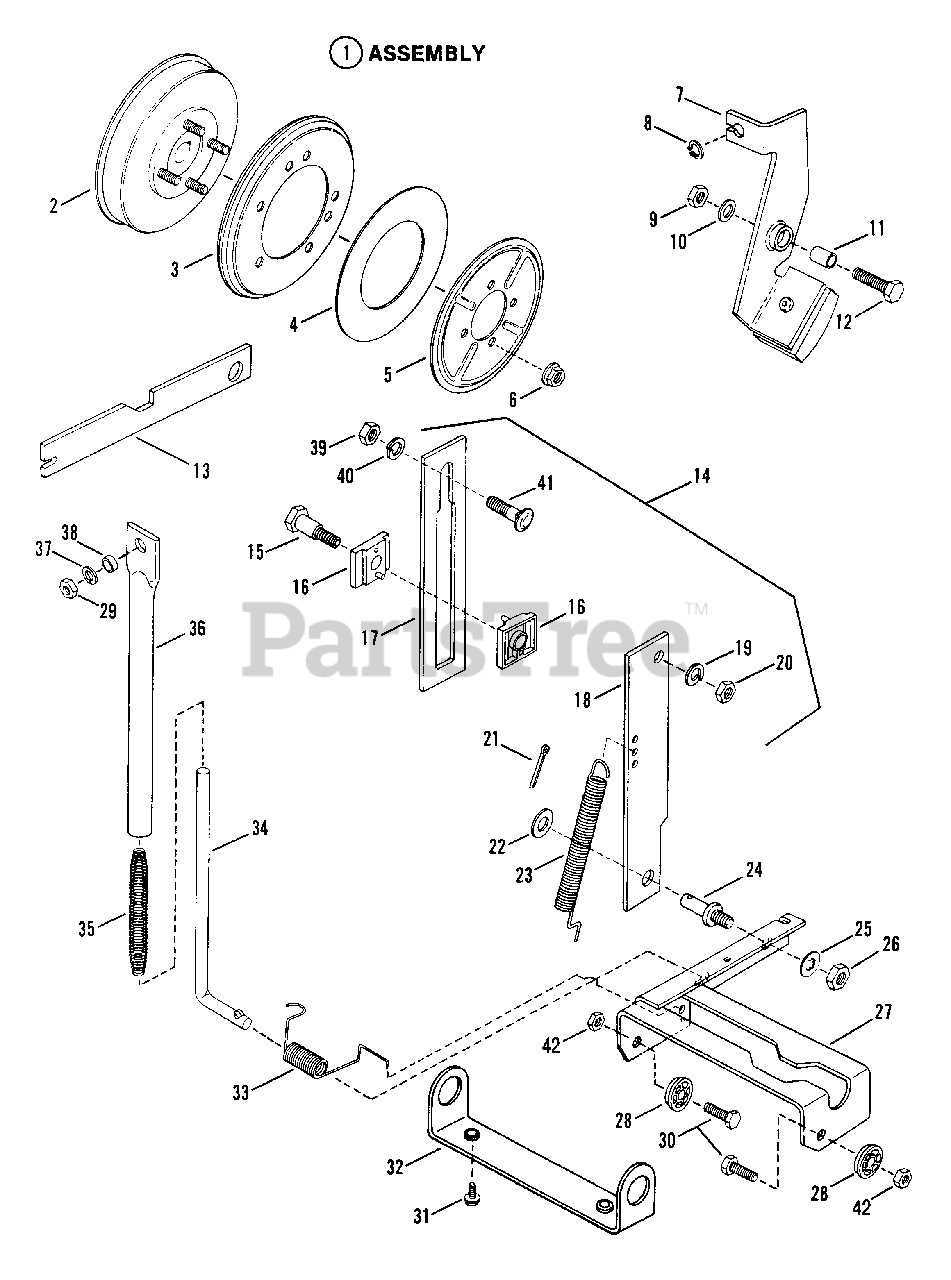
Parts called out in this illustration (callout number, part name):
1	ASSEMBLY, Smooth Clutch
2	HUB, Driven Disc
3	DISC, Driven
4	WASHER, Thrust
5	PLATE
6	NUT, 5/16 - 18 Hex Flange Lock
7	ASSEMBLY, Brake Lever
8	RING, Retaining
9	NUT, 1/4-28 Hex Lock
10	WASHER, 1/4 Flat
11	SPACER
12	SCREW, 1/4-28 x 1" Hex Head Cap
13	TOOL, Smooth Clutch
14	ASSEMBLY, Guide & Link
15	BOLT, 5/16-18 Shoulder
16	SLIDE-HALF
17	GUIDE, Clutch Link
18	LINK, Clutch
19	WASHER, 5/16 Split Lock
20	NUT, 5/16-18 Hex
21	COTTER-PIN, 3/32 x 1"
22	WASHER, 3/8" Flat
23	SPRING, Clutch Brake
24	STUD, Clutch Link
25	WASHER, 3/8 Internal Tooth Lock
26	NUT, 3/8 Hex
27	LIFT, Yoke
28	BEARING, Yoke
29	NUT, 5/16-24 Hex Center Lock
30	SCREW, 5/16-24 x 3/4" Hex Head Cap
31	SCREW, 3/8-16 x 1/2" Self-Tapping
32	COLLAR, Yoke
33	SPRING
35	SPRING
37	WASHER, 5/16 Flat
38	ROLLER
39	NUT, 3/8-16 Hex
40	WASHER, 3/8 Split Lock
41	BOLT, 3/8-16 x 3/4" Short Neck Carriage
42	NUT, 5/16-24 Hex Lock
